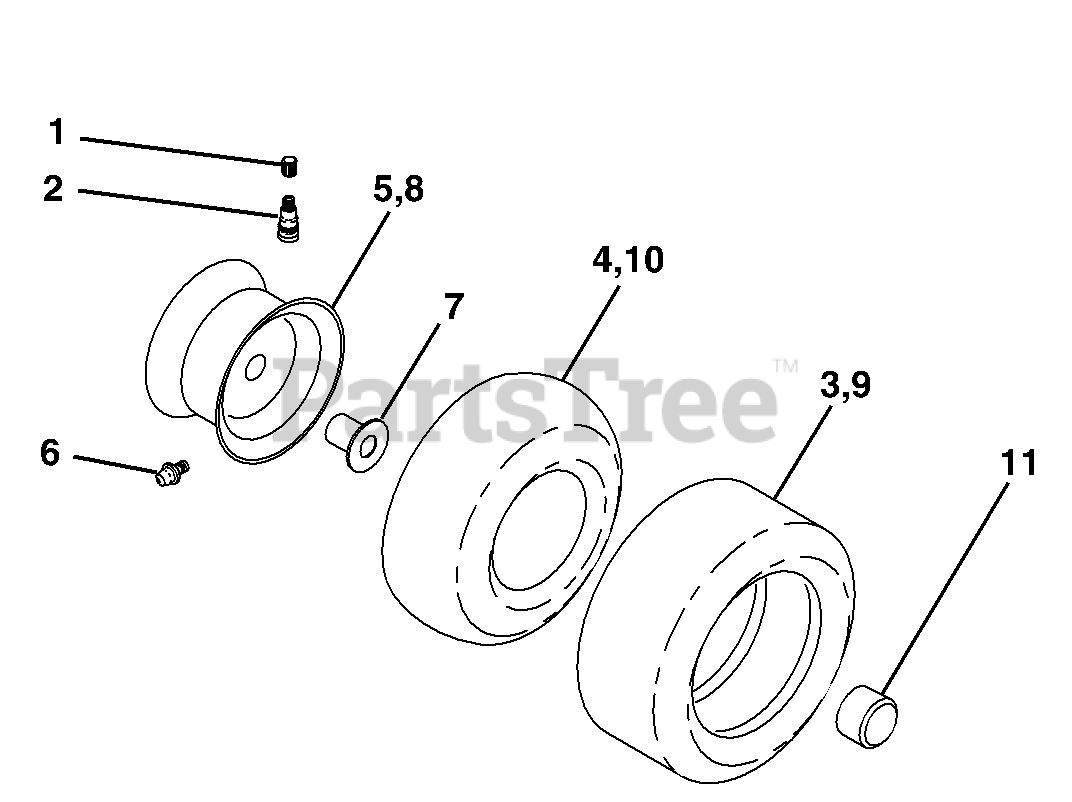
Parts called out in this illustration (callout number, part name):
1	Cap, Tire valve
2	Stem, Valve
3	Tire, Front
4	Tube, Front
5	Rim assembly, 6"
6	Fitting, Grease
7	Bearing, Flange
8	Rim assembly, 8"
9	Tire, Rear
10	Tube, Rear
11	Cap, Hub Axle
